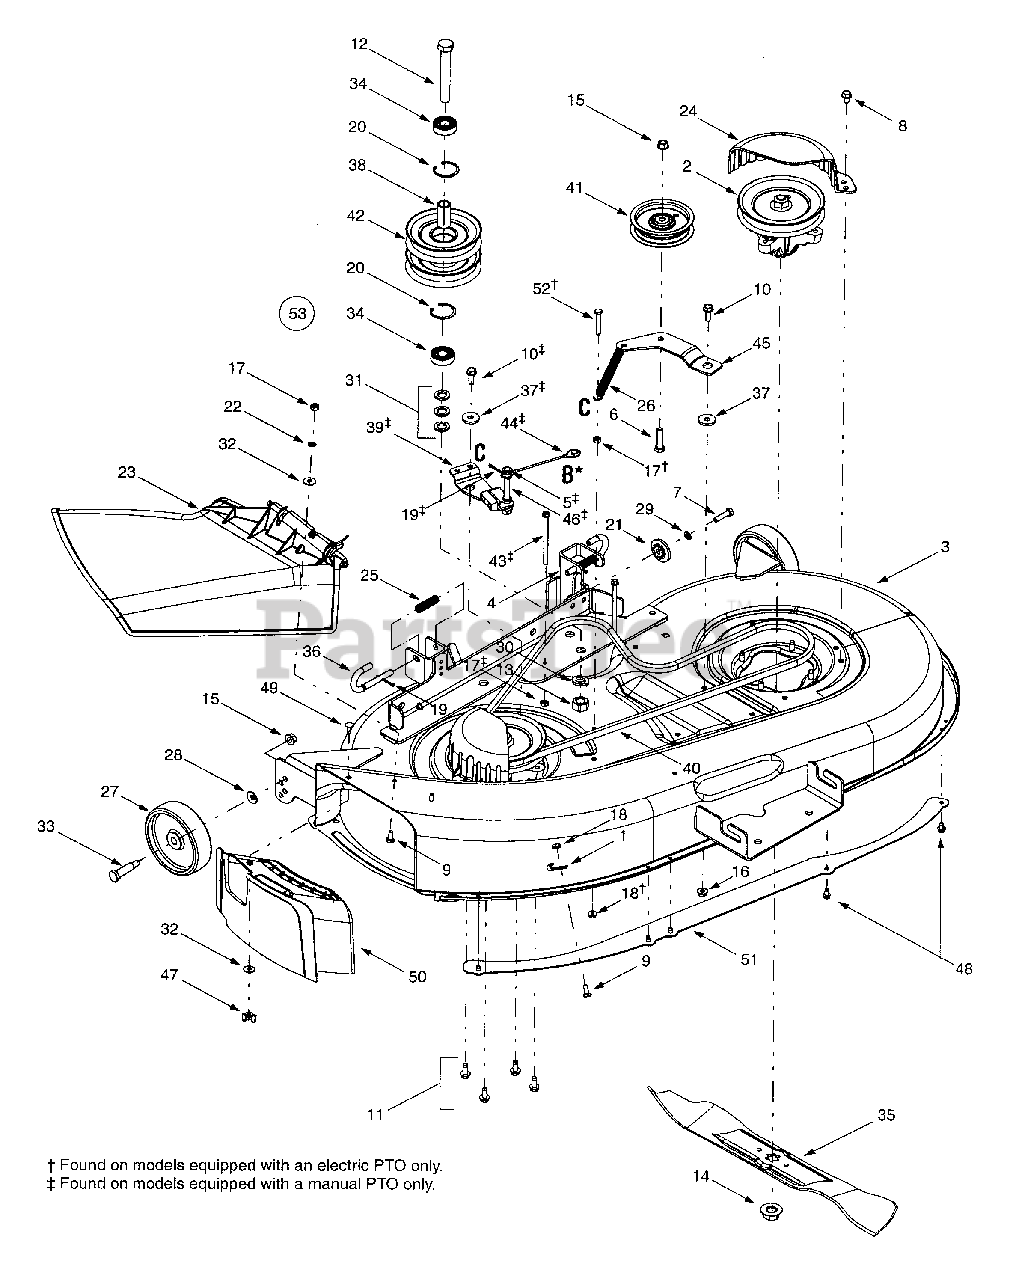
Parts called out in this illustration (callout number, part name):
1	Retainer Hook
2	Spindle Assembly, 5.75 Dia.
5	Flat Washer, .385 x .62 x .063
6	Hex Cap Screw, 1/4-20 x 1.5
7	Hex Cap Screw, 5/16-18 x 1.25
8	Self-tapping Screw, 5/16-18 x .625
9	Hex Cap Screw, 1/4-20 x .62
10	Hex Head Washer Screw, 5/16-18 x .875
11	Self-tapping Screw, 5/16-18 x .75
12	Hex Cap Screw, 5/8-18 x .875
13	Hex Nut, 5/8-18
14	Hex Flange Nut, 5/8-18
15	Flange Lock Nut, 3/8-16
16	Flange Lock Nut, 5/16-18
17	Hex Nut, 1/4-20
18	Hex Flange Lock Nut, 1/4-20
19	Cotter Pin, 1/8 x 1.25
20	Internal Snap Ring
21	Deck Adjustment Gear
22	Push Nut. .25 x .5
23	Side Discharge Chute Assembly
24	Belt Cover
25	Compression Spring, .406 x .531 x 1.75
26	Extension Spring, .50 x 4.74
27	Deck Wheel, 5 x 1.38
28	Bell Washer, .401 x .87 x .063
29	Lock Washer, 5/16
30	Lock Washer, 5/8
31	Flat Washer, .64 x 1.0 x .12
32	Bell Washer, .265 x .75 x .062
33	Shoulder Screw, .498 x 1.53
34	Bearing, .625 x 1.574 x .470
35	Three-in-one Blade, Star Center, 21.23"
36	Deck Release Pin
37	Shoulder Spacer, .625 x .324
38	Spacer, .635 x .88 x 1.72
39	Deck Brake Assembly
40	Deck Belt
41	Idler Pulley, 3.5
42	Double Pulley, 5.0
43	Self-tapping Screw, 1/4-20 x 4.0
44	Brake Cable, 5.05
46	Pin, 3/8-16, 3/8 x 3.27
47	Wing Nut, 1/4-20
48	Self-tapping Screw, 1/4-20 x .5
49	Carriage Screw, , 1/4-20 x .62
50	Mulch Plug
52	Hex Cap Screw, 1/4-20 x 1.75
